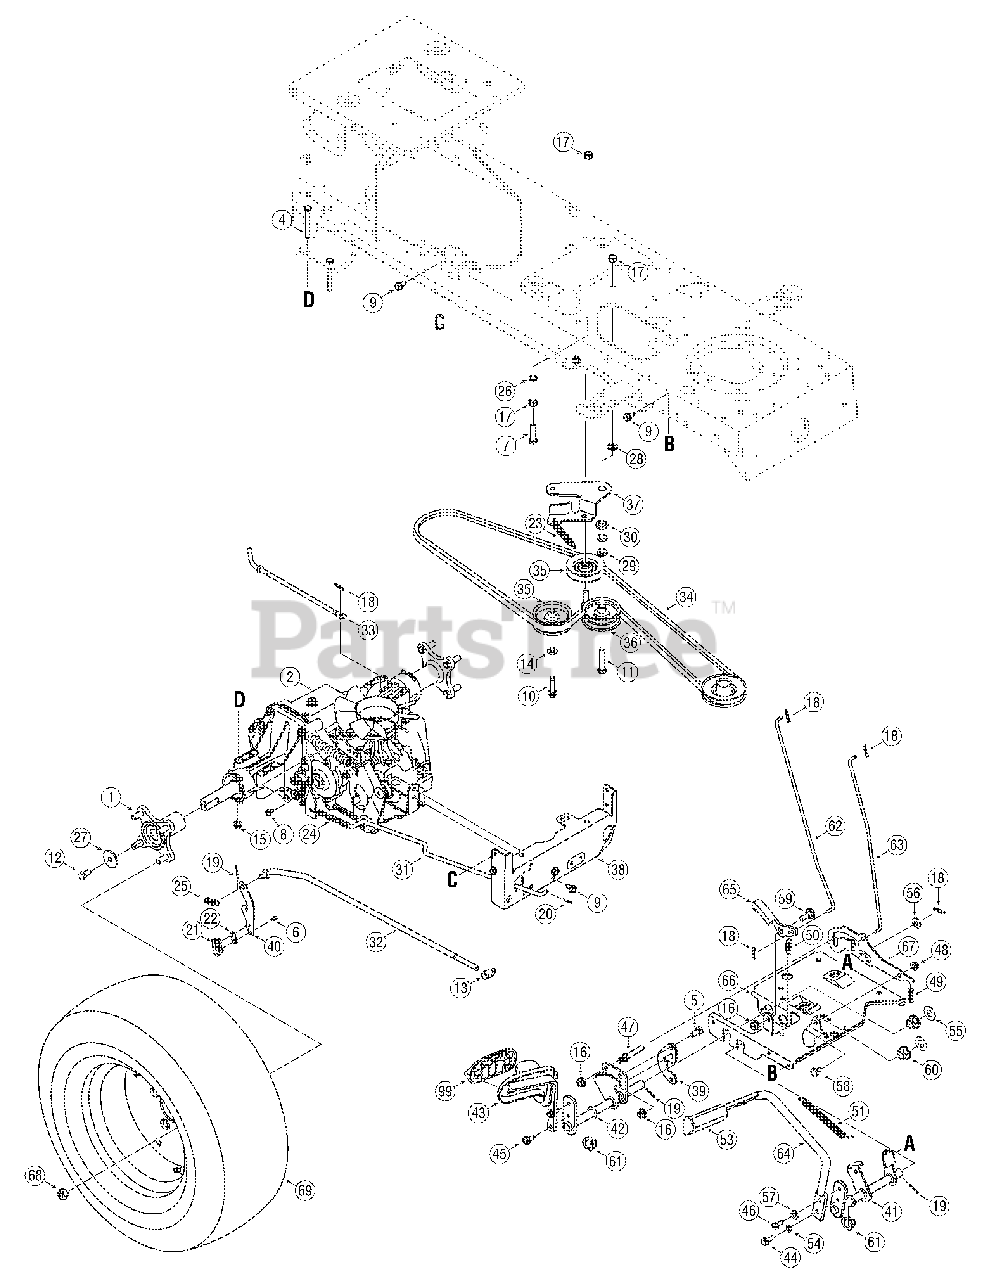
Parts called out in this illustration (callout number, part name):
1	Wheel Hub Assembly
2	Hydro GT Transmission Assembly
4	HH Cap Screw 5/16-18 x 2.75
5	HH Cap Screw 3/8-16 x.75
6	AB Screw #8-18 x.500
7	HH Cap Screw 3/8-16 x 1.50
8	TT Screw 1/4-20 x.500
9	AB Screw 5/16-12 x.750
10	TT Sems Screw 3/8-16 x 1.500
11	HH Cap Screw 3/8-16 x 2.25
12	HH Cap Screw 3/8-16 x.750
13	Ferrule 3/8-24 x.375
14	Jam Nut
15	Flange Lock Nut 5/16-18
16	Flange Lock Nut 3/8-16
17	Hex Nut 3/8-16
18	Cotter Pin.072 x 1.13
19	Cotter Pin 3/32 x 1.0
20	Cotter Pin 3/32 x.750
21	Short Spring Switch
22	Insulator Nut Plate
23	Extension Spring.770 x 3.720
24	Extension Spring.59 x 4.00
25	Extension Spring 3/8 x 1.44
26	Lock Washer 3/8
27	Flat Washer.390 x 1.500 x.134
28	Flat Washer.385 x 1.0 x.135
29	Flat Washer.407 x.812 x.135
30	Shoulder Spacer 1.00 x.38 x.38
32	Control Rod
33	Bypass Rod
34	Drive Belt
35	V-Type Idler Pulley 3.06
36	Flat Idler Pulley 2.75
44	TT Screw 5/16-18 x.875
45	LD Screw 5/16-18 x.750
46	TT Screw 5/16-18 x.750
47	Pin 3/8-16 x 2.68
48	Flange Lock Nut 5/16-18
49	Compression Spring.405 x 1.17
50	Extension Spring.50 x 1.41
51	Extension Spring.50 x 6.37
52	Drive Pedal Pad
53	Brake Control Pad
54	Lock Washer 5/16
55	Flat Washer.64 x 1.24 x.06
56	Flat Washer.385 x.870 x.092
57	Flat Washer.344 x.750 x.120
58	Shoulder Screw.437 x.162
59	Shoulder Screw.50 x.27 x 3/8-16
60	Hex Flange Bearing
61	Hex Flange Bearing.628 ID Split
62	Brake Lock Control Rod
63	Cruise Control Rod
67	Hydro Lockout Bracket
68	Lug Nut 7/16-14
69	Air Valve
